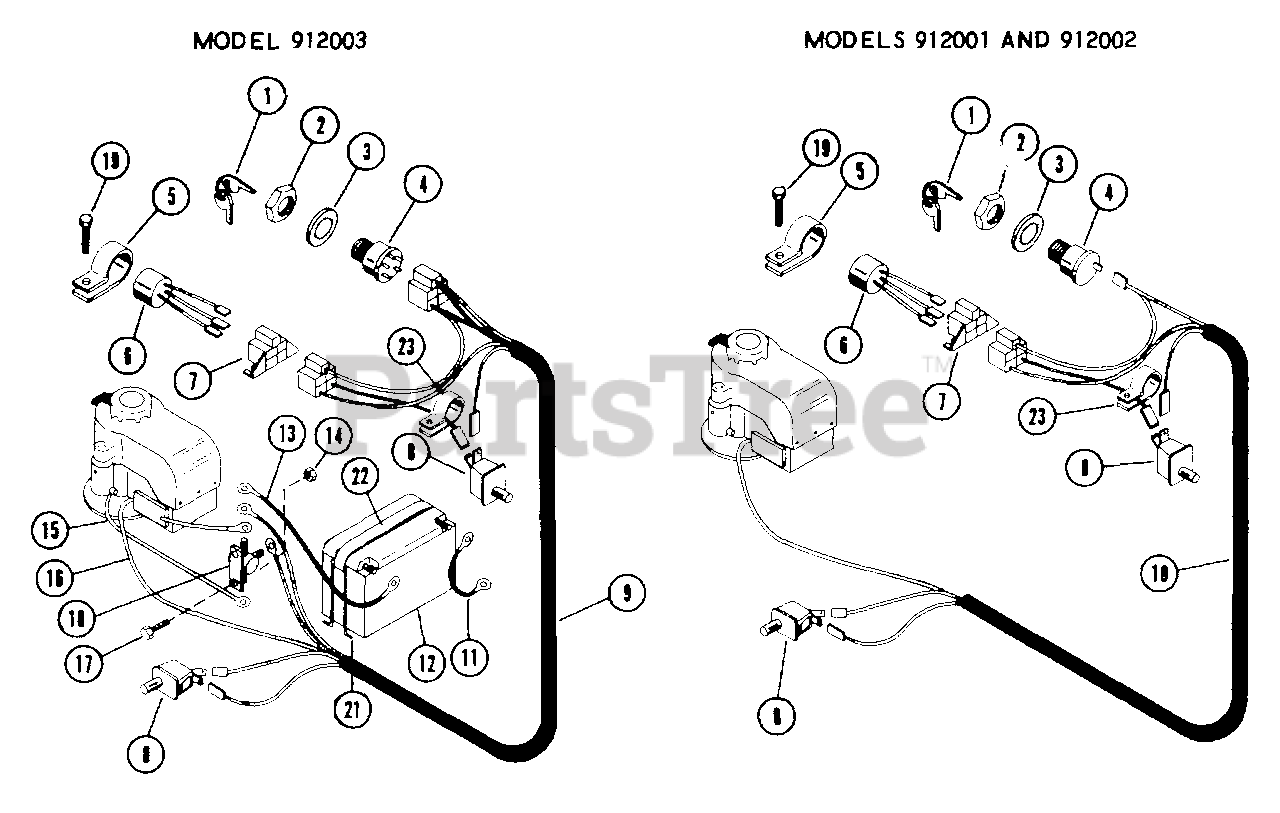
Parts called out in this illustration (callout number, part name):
1	KEYS
2	NUT .625-32 ALUM
3	WSHR-LK-INT .625X.045 PL
4	IGNITION SWITCH ASSEMBLY
4	KEY SWITCH ASSEMBLY
6	MODULE T
7	CONNECTOR
8	SHIFT LINK
9	WIRING HARNESS
10	WIRING HARNESS
11	GROUND CABLE
12	BATTERY
13	POSITIVE BATTERY CABLE
14	NUT-LK-CTR .250-20 PL
15	GROUND CABLE
16	CHARGING WIRE
17	BLT-HEX .25-20X.50 PL GR2
18	SOLENOID
19	BLT-SERHFWH .31-18X.50 PL
21	HOOK
22	RUBBER BAND
